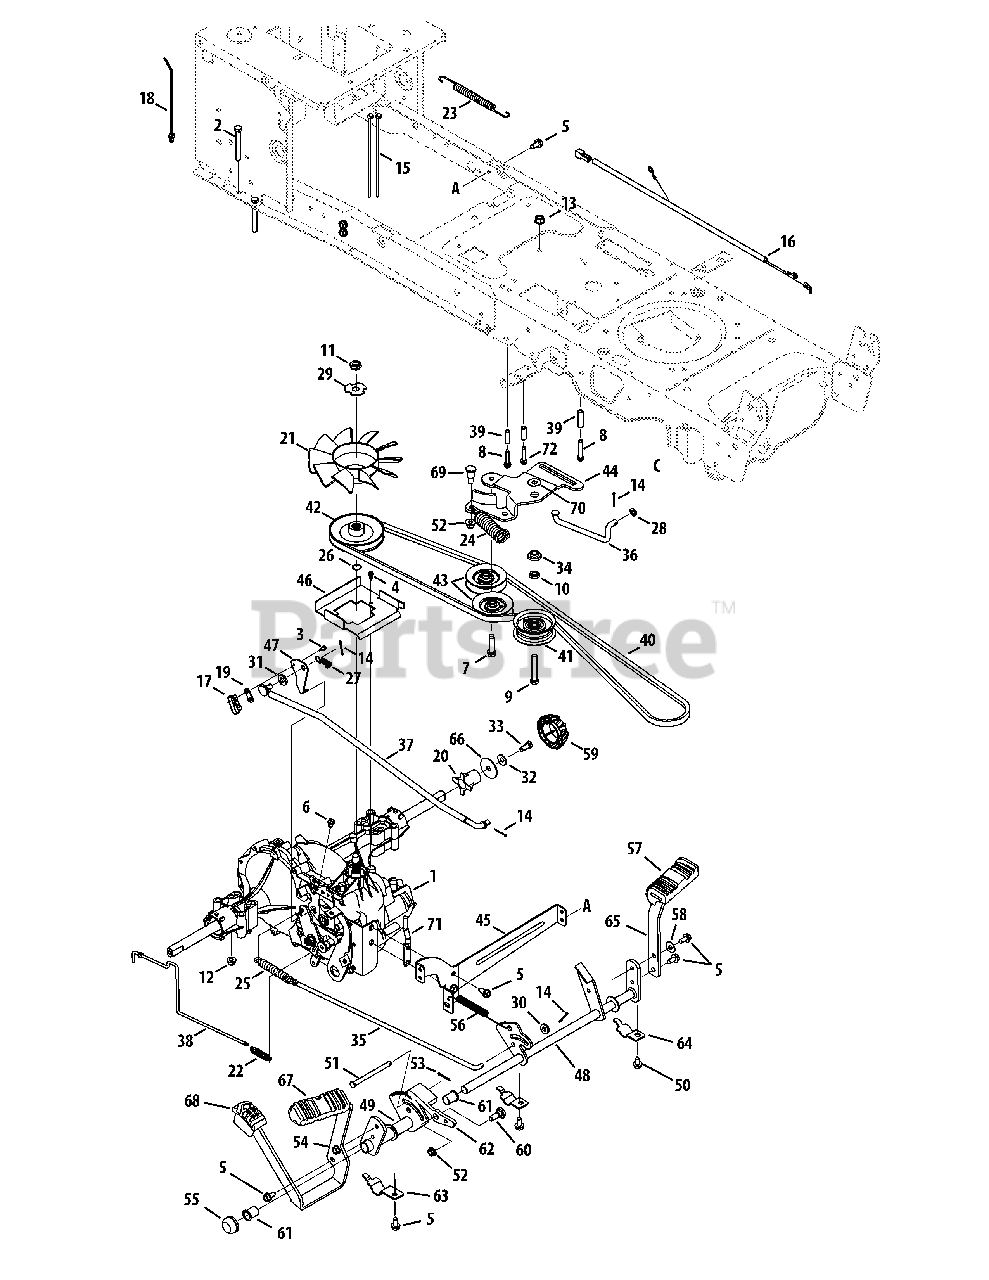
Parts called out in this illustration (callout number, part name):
1	Transmission, Hydro-Gear 0510
2	Hex Screw, 5/16-18, 2.75, Gr5, Std
3	Screw, #8-18, 0.500,
4	Screw, #10-16, 0.500
5	Screw, Self-tapping, 5/16-18, .750
6	Screw, Self-tapping, 1/4-20, 0.375
7	Screw, Self-tapping, 3/8-16, 1.500
8	Screw, Self-tapping, 1/4-20, 1.625
9	Hex Screw, 3/8-16, 2.25, Gr5
10	Nut, Jam, 7/16-20, Gr2
11	Nut, Jam Lock, 1/2-20, Gr5, Nylon
12	Nut, Flange Lock, 5/16-18, Nylon
13	Nut, Flange Lock, 3/8-16
14	Pin, Cotter, 3/32, 1.0
15	Cable, Tie, 3/16 x .05 x 7.4
16	Jumper Harness, Ground & Reverse
17	Switch, Spring, Short
18	Tie, Cable, Push Mount 7.5
19	Plate, Insulator Nut
20	Sleeve, .765 Id x 1.500
21	Fan, Hydro
22	Spring, Extension, .48 Od x 2.03
23	Spring, Extension, .500 Dia x 12.6
24	Spring, Extension, 1.00 Dia x 4.75
25	Spring, Extension, .59 Od x 4.00
26	Ring, Wire
27	Spring, Extension, .375 Od x 1.44
28	Washer, Flat, .330 x .630 x .0635
29	Washer, Lock, Transmission Hydro
30	Washer, Flat, .344 x .750 x .120
31	Washer, Flat, .407x.812x.135, Ht
32	Washer, Bell, .340 x .872 x .060
33	Hex Screw, 5/16-24, .750, Gr5, Lock
34	Spacer, Shoulder, 1.375 x .380 x .183
35	Rod, Brake, LT Hydro
36	Rod, Transmission, Bypass
37	Rod, Control, Hydro
38	Rod, Hydro Bypass
39	Spacer, .260 x .372 x 1.420
40	Belt, V-Type 4L X 78.9 LG
41	Pulley, Idler, Flat 2.75 OD
42	Pulley, Input, 4.13 Dia
43	Pulley, Idler, V-Type x 3.06
44	Bracket, Idler, Center Double
45	Bracket, Mount, Hydro
46	Bracket, Support, Belt Disengage
47	Bracket, Actuator, Switch
48	Control Assembly, Brake
49	Bracket Assembly, Pedal, Hydro
50	Screw, Self-tapping, 5/16-18, 0.625,
51	Pin, Clevis, 5/16 x 3.985
52	Nut, Flange Lock, 3/8-16, Nylon
53	Pin, Cotter, Bow-Tie 72
55	Cap, Push 5/8
56	Spring, Extension, .63 Dia x 4.95
57	Pad, Pedal, Brake
58	Washer, Bell, .340 x .872 x .060
59	Cap, Hub
60	Bolt, Shoulder, .500 x .270, 3/8-16
61	Bearing, Flange, .630 x .695 x .60
62	Latch, Cruise
63	Bracket, Support, Pedal Strap
64	Bracket, Support, Pedal Strap 5/8
65	Bracket, Pedal, Brake
66	Washer, Flat, .350 x 1.59 x .062
67	Pad, Pedal, Forward
68	Pad, Pedal, Reverse
69	Screw, Shldr, .50 x .685 3/8-16
70	Washer, Flat, .385 x 1.0 x .030
71	Belt Keeper Rod
72	Screw, Self-tapping, 1/4-20 x 1.75
